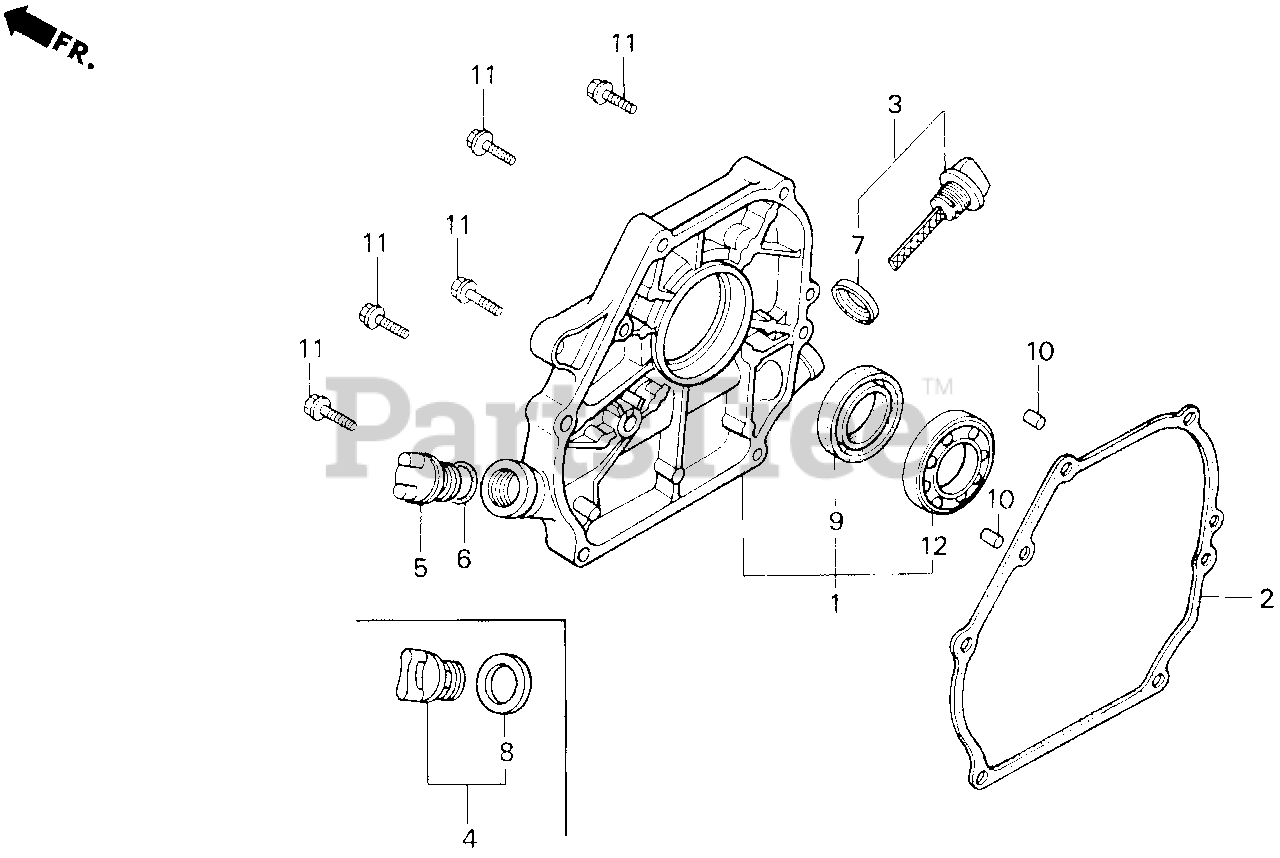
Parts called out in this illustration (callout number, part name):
1	COVER ASSY., CRANKCASE
2	GASKET, CASE COVER (NON-ASBESTOS)
3	CAP ASSY., OIL FILLER (GRAY)
4	CAP ASSY., OIL FILLER
5	CAP, OIL FILLER
6	GASKET, OIL FILLER CAP
7	GASKET, OIL FILLER CAP
8	GASKET, OIL FILLER CAP
9	OIL SEAL (25X41X6)
10	PIN, DOWEL (8X14)
11	BOLT, FLANGE (8X32)
12	BEARING, RADIAL BALL (6205)
